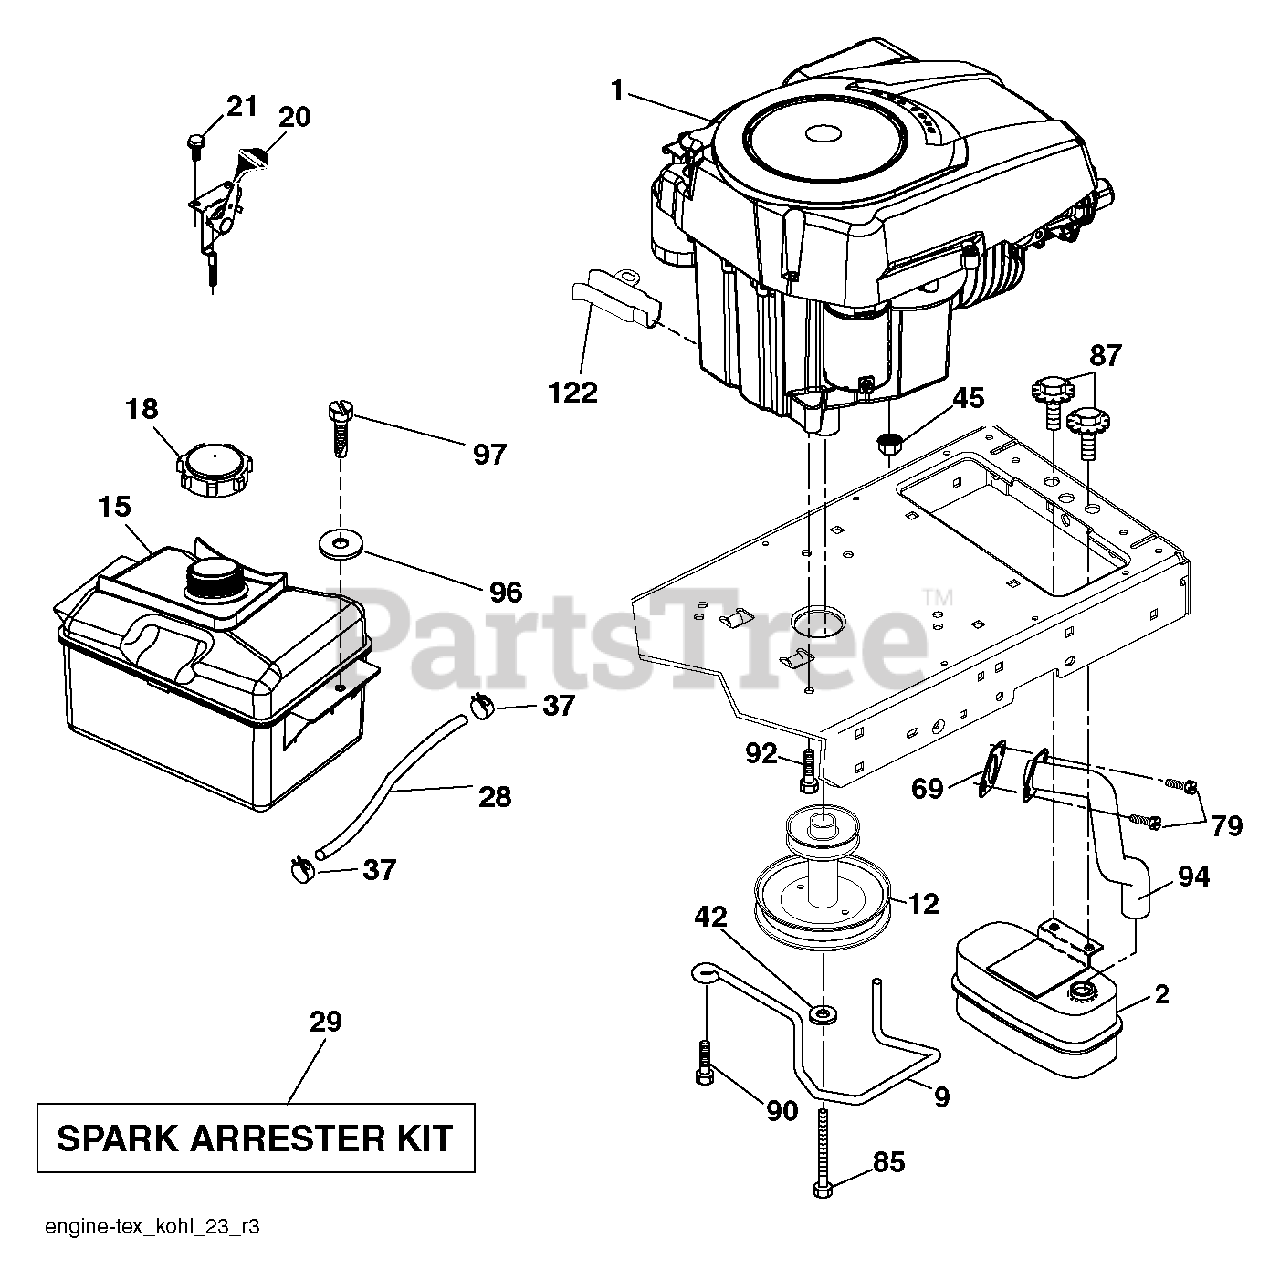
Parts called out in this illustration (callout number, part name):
2	MUFFLER.SINGLE.CYL.KOHL/B&S
9	KEEPER.BELT.ENGINE.3.25 (3 2)
12	PULLEY ENGINE
15	RP TANK FUEL FRT 1.5 GAL
18	CAP ASM.FUEL.2.25"FR.
20	CONTROL.TH/CK.C.
21	SCREW.#10 X 0.750.BOS
28	LINE.FUEL.20"FRONT.EMI
29	KIT.SPARK ARRESTOR 794945 B&S
37	HOSE CLAMP
42	LOCKWASHER
45	NUT
69	GASKET.EXHAUST.KOHLER
79	SCREW.SOCKET HD.5/16-1
85	BOLT HEX 7/16-20X4-1/4"
87	BOLT.5/16-18UNCX1.W/SEMS.BLK
90	SCREW 3/8-16X1
92	SCREW 3/8-16X1
94	RP.TUBE.EXHAUST.KOHL.COURAGE
97	SCREW HEXWSHR 1/4-20X3/4
122	EXTENSION DRAIN OIL
